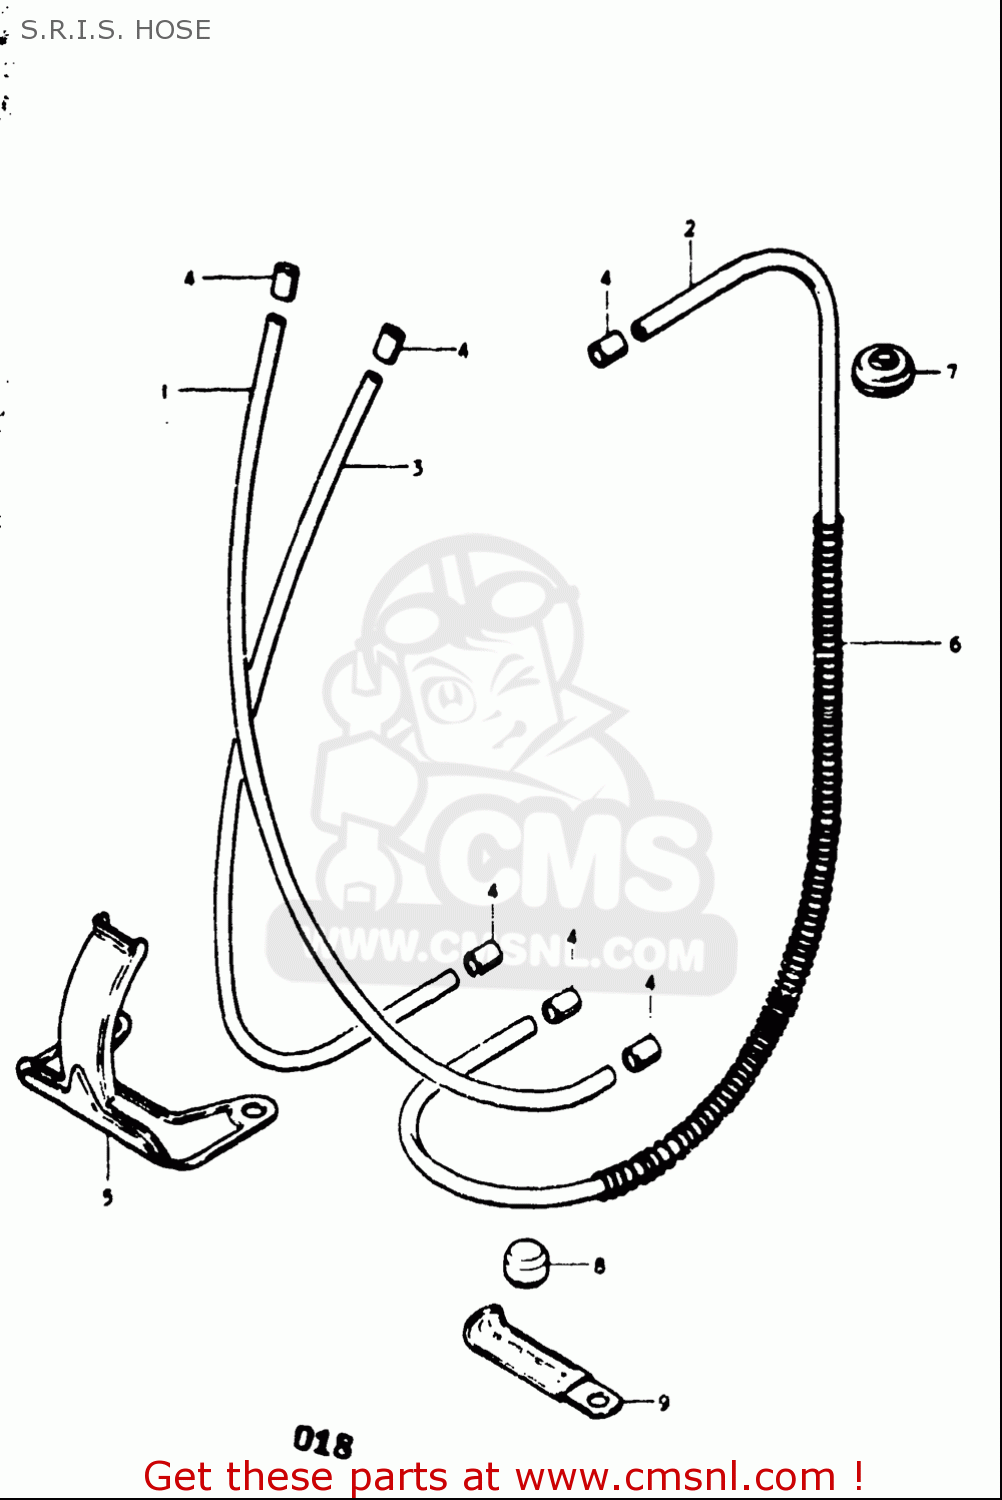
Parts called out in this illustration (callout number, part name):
1	HOSE(2X5X600)
2	HOSE(2X5X600)
3	HOSE(2X5X600)
4	CLIP
7	GROMMET
8	PAD,CYLINDER HEAD
9	CLAMP
